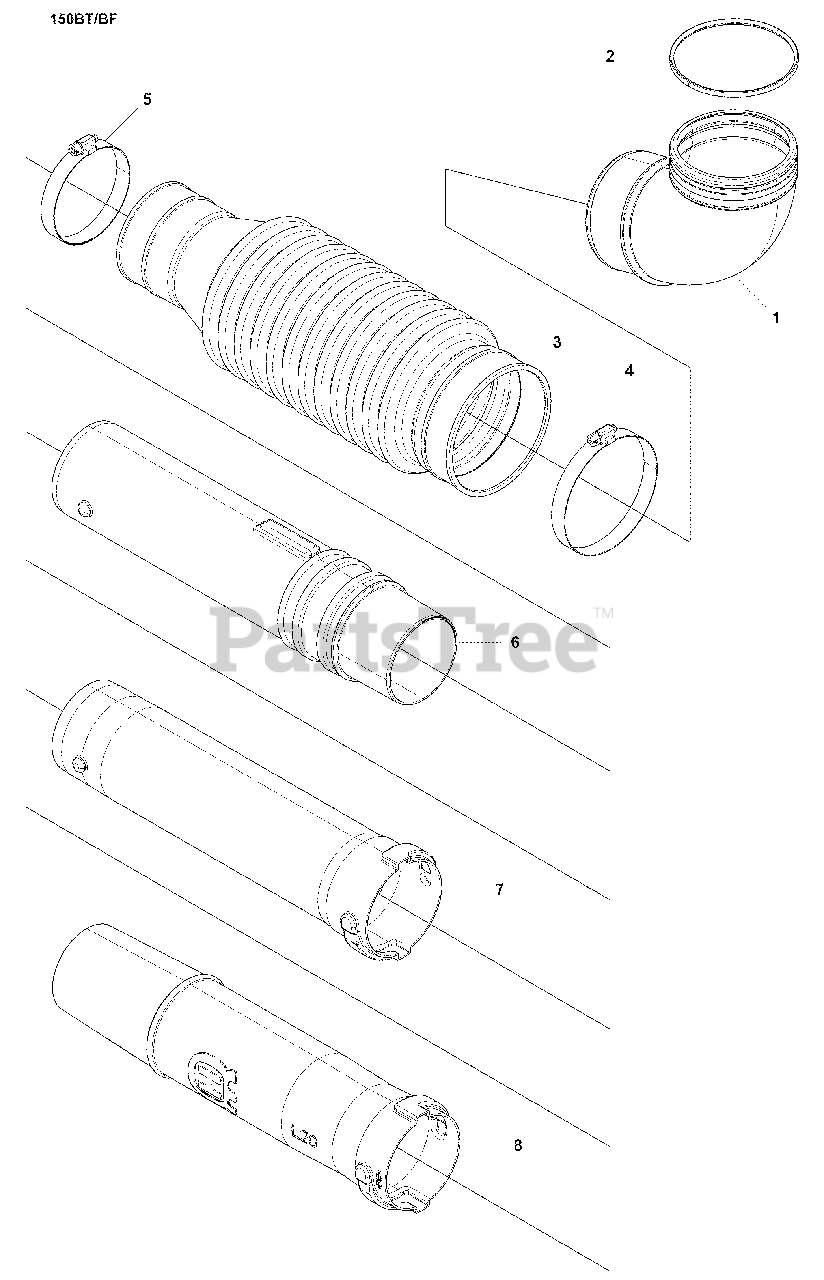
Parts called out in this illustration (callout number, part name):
1	PIPE BEND
2	O-RING
3	BELLOWS
4	CLAMP(F115)
6	SWIVEL JOINT
7	PIPE STRAIGHT
